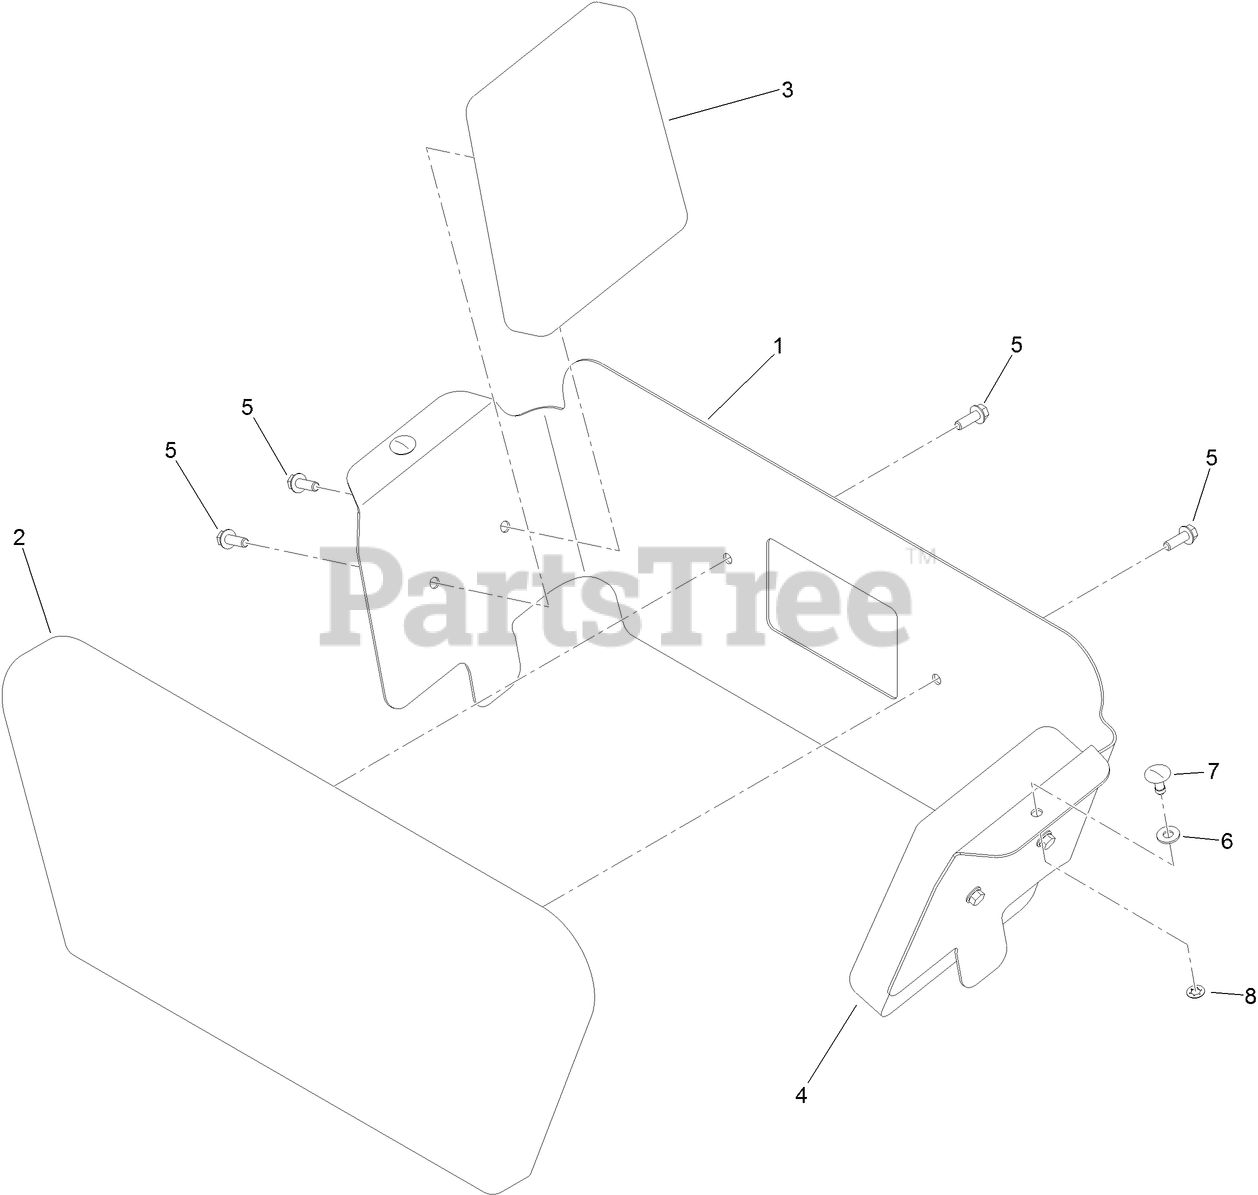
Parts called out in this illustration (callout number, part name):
1	BRACKET-PAD, KNEE
2	PAD-KNEE, CENTER
3	PAD-KNEE, SIDE (LH)
4	PAD-KNEE, SIDE (RH)
5	SCREW-HHF
6	WASHER-FLAT
7	STUD-1/4 TURN
8	RETAINER-STUD
